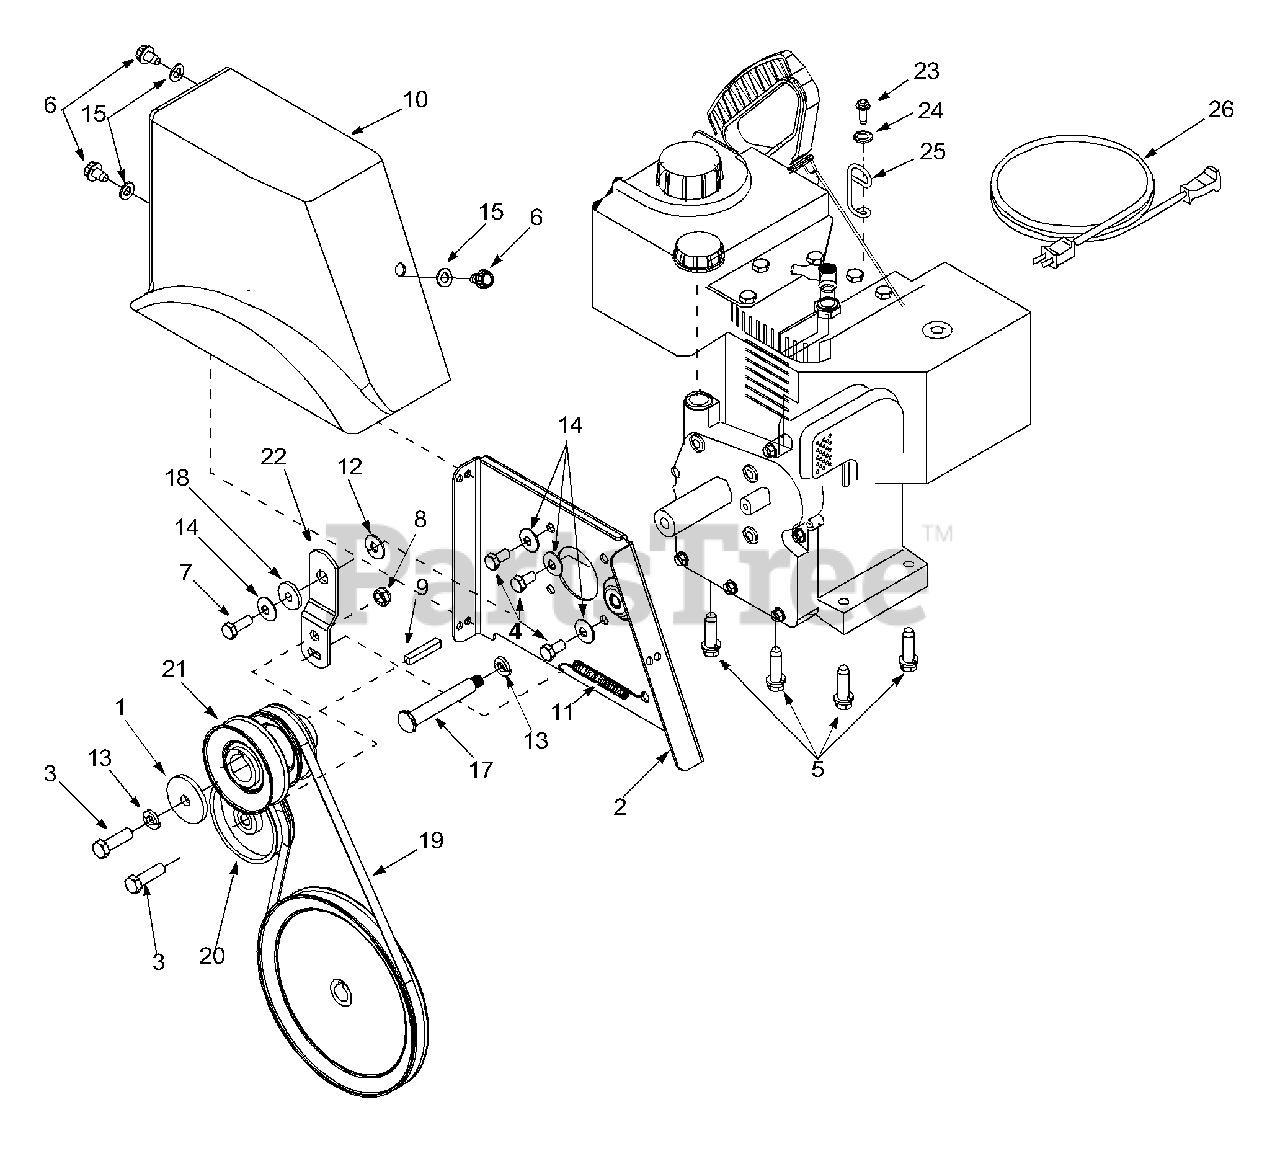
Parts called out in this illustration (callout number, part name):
1	Washer
4	Hex Screw 5/16-24 x .625"
5	TT Sems Screw
6	TT Screw 5/16-18 x 0.5"
7	Hex Lock Screw 5/16-24 x .875"
8	Jam Nut
10	Belt Cover
11	Extension Spring
12	5/16 Washer
13	Lock Washer
14	Beleville Washer
15	Flat Washer
17	Shoulder Screw
18	Shoulder Spacer
19	V-Belt
20	Flat Idler
21	Double Pulley
22	Idler Bracket
23	Hex Lock Nut: 1/4-20
24	Cable Guide
25	Flat Washer
26	Extension Cord: 110V, 3-prong
